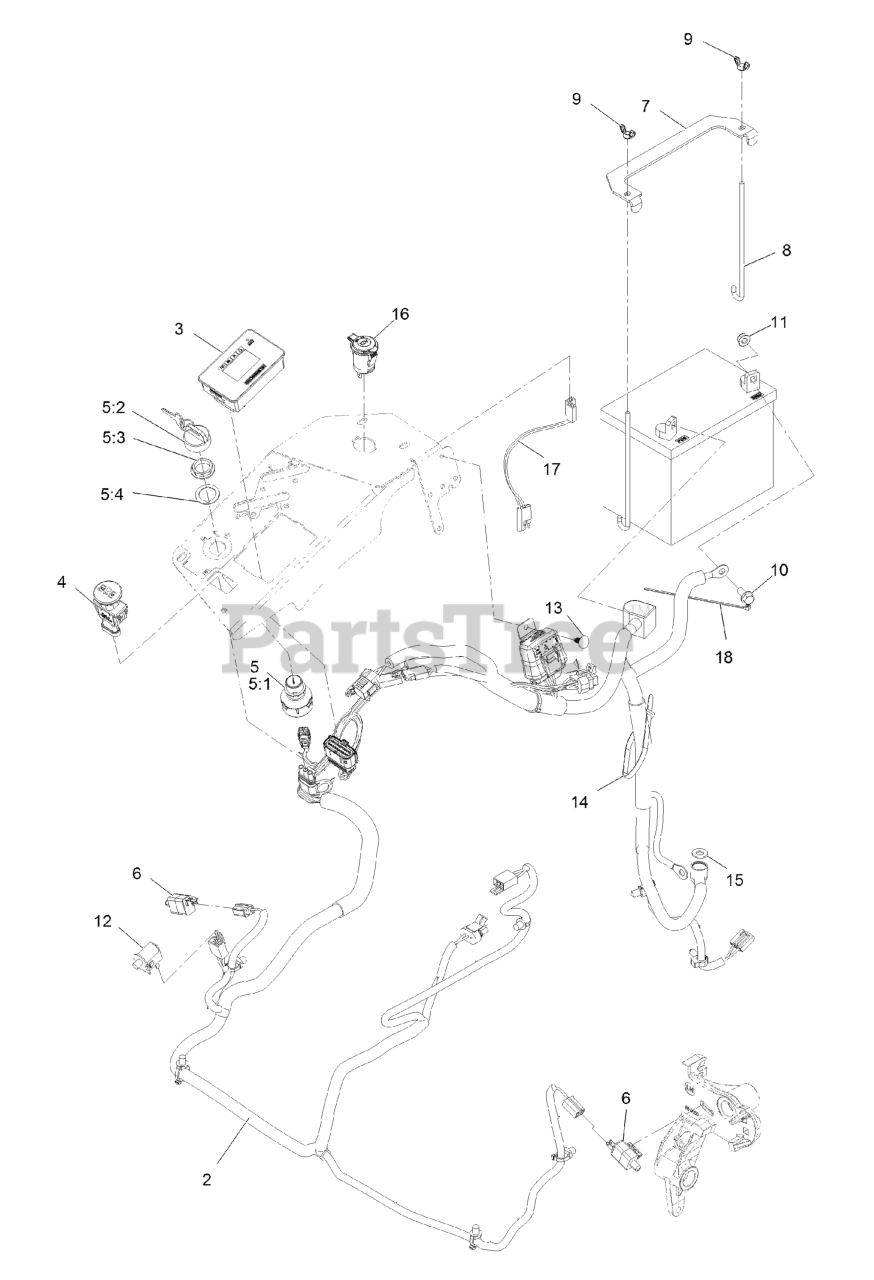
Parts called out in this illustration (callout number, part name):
2	HARNESS-WIRE, MAIN
2:2	FUSE-BLADE, 10 AMP
2:3	FUSE-BLADE, 15 AMP
2:4	FUSE-BLADE, 25 AMP
2:5	CAP-PLUG
3	FUEL/HOUR METER ASM
4	KEYS-IGNITION (SPARE PAIR
4	KEY-IGNITION
6	STRAP-TIE DOWN, BATTERY
7	BOLT-HOLDDOWN
8	WINGNUT
10	CABLE-BATTERY, NEGATIVE
11	SCREW-HHF
12	NUT-HF, NI
13	TIE-CABLE
14	SWITCH-BAIL
16	SWITCH-PTO, 10 AMP
17	SCREW-HWH
18	CABLE-BATTERY, POSITIVE
19	WASHER-FLAT
20	TIE-PLASTIC
22	INDICATOR-LED, RED
23	HARNESS-LIGHT, INDICATOR
24	CLAMP-HOSE
25	INSULATOR-BATTERY
26	INSULATOR-SOLENOID
